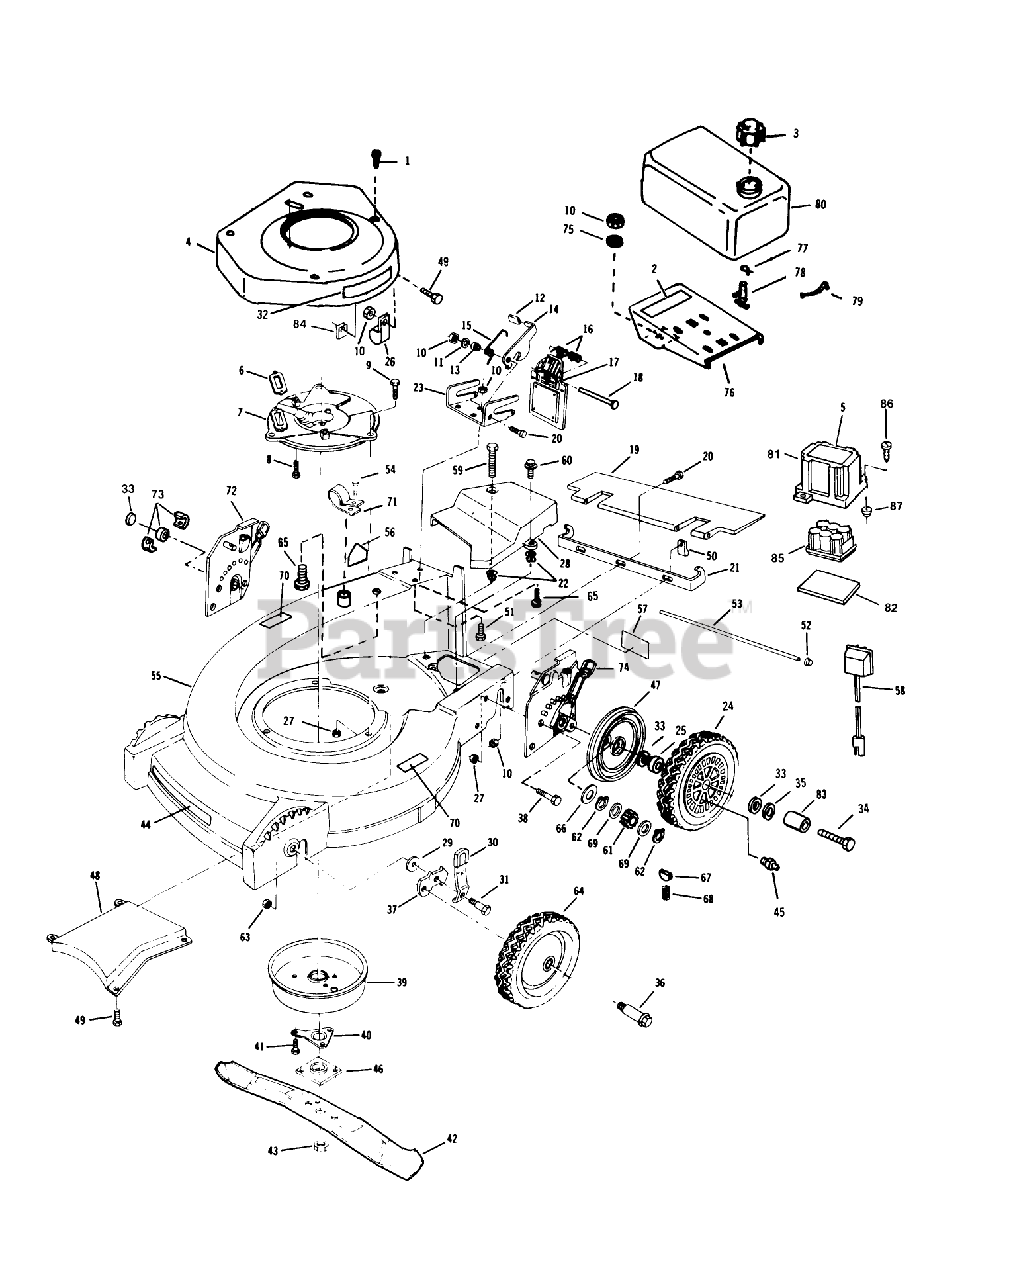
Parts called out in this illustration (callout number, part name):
1	SCREW - SELF TAPPING
3	FUEL CAP & INSERT
8	SCREW V
9	SCREW-HH
10	LOCKNUT E
12	KNOB (S&R)
15	SPRING
16	SPRING ASOC
18	ROD (RB&W)
19	T/SHIELD SM&P
27	NUT-LOCK F
29	WASHER
30	SPRING ARM ASM
31	BOLT
33	WASHER
35	SPACER
36	BOLT-SHOULDER
39	MUFFLER COVER F
40	SUPPORT F
41	SCREW
43	NUT-BLADE
44	DISCOUNTED
45	FITTING LINCOLN
46	PLATE AND COLLAR ASM
48	BAFFLE CHUTE PL
51	SCREW
54	SCREW LAWRENCE
60	SCREW
61	PINION BROCKWAY
62	RET RING
63	LOCKNUT
65	SCREW HEX WASHER
66	THRUST WASHER
67	KEY
68	SPRING
69	SPACER/GR ALGHNY
73	REAR AXLE BEARING
75	WASHER
76	BRACKET - TANK
77	CLAMP - HOSE S
78	VALVE&SCREEN SM
79	SPRING
82	PAD-BATTERY
84	PUSHNUT F
86	SCREW - SELF TAPPING
87	NUT-CLIP
